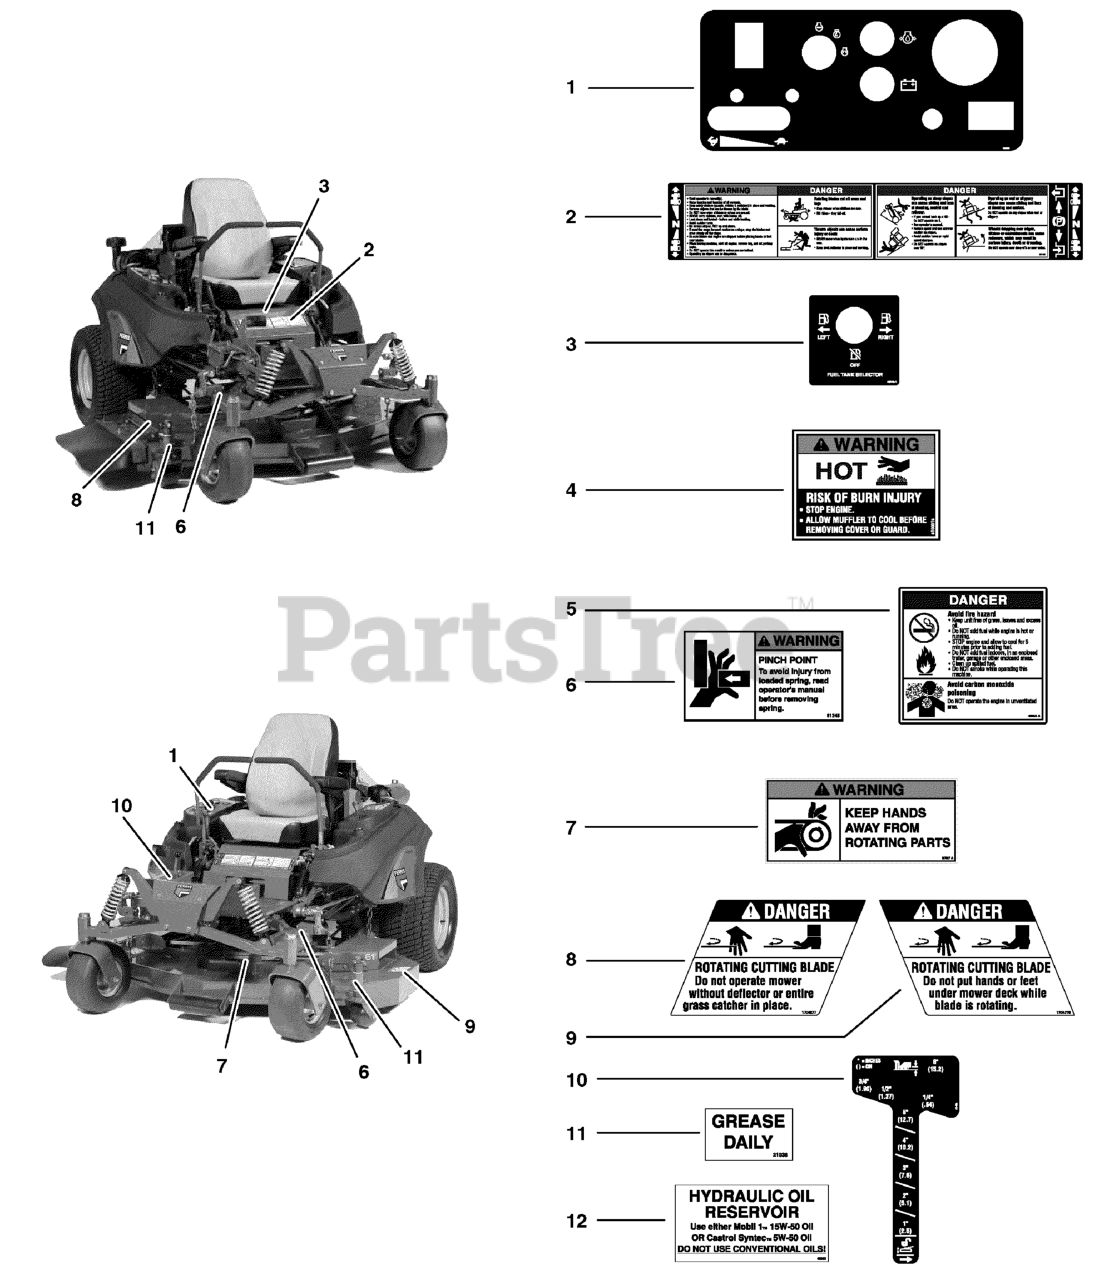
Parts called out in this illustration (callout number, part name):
1	DECAL, Control Panel, Gas
2	DECAL, Main
3	DECAL, Fuel Selector
4	DECAL, Warning, Burn
5	DECAL, Danger
6	DECAL, Pinch Point
7	DECAL, Warning
8	DECAL, Danger (Chute In Place)
9	DECAL, Danger (Hand Under Deck)
10	DECAL, Height of Cut
11	DECAL, Grease Daily
12	DECAL, Oil Reservoir
